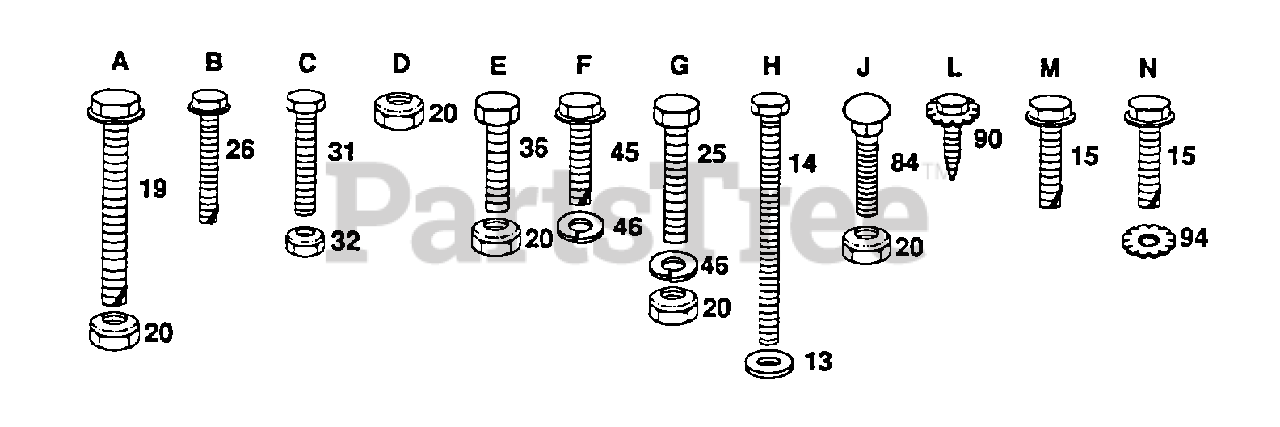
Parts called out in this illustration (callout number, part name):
13	LOCKWASHER
14	SCREW HEX HD CAP
15	SCREW
19	BOLT
25	BOLT
26	SCREW
31	BOLT
35	STRAP TORQUE
45	SCREW
46	WASHER
84	BOLT
94	LOCKWASHER
